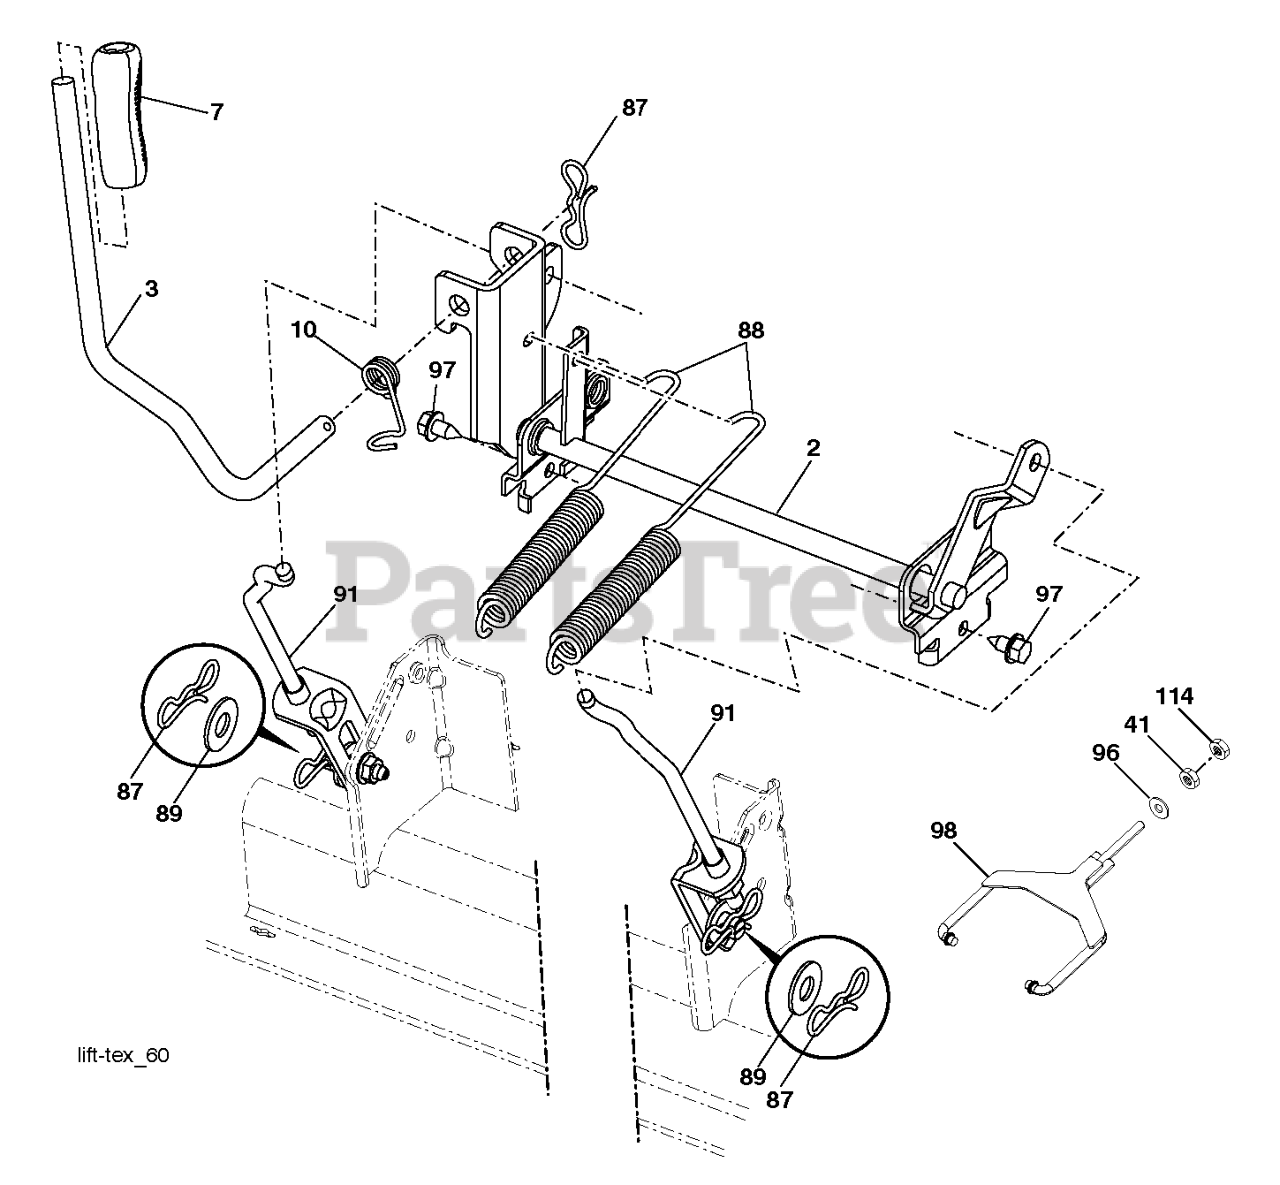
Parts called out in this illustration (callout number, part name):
2	SHAFT.ASM.CROSS.LIFT
3	Levers
7	GRIP.HANDLE.LIFT.PVC.BLACK
10	SPRING.TORSION.LIFT.HANDLE
41	NUT.LIFT LNK.7/16-2
87	PIN.COTTER.7/16.BOW TI.
89	WASHER.CLEAR.ZINC
97	SCREW, 3/8-16X3/4
98	DECK ATTACHMENT FRONT LINK WEL
114	NUT **
